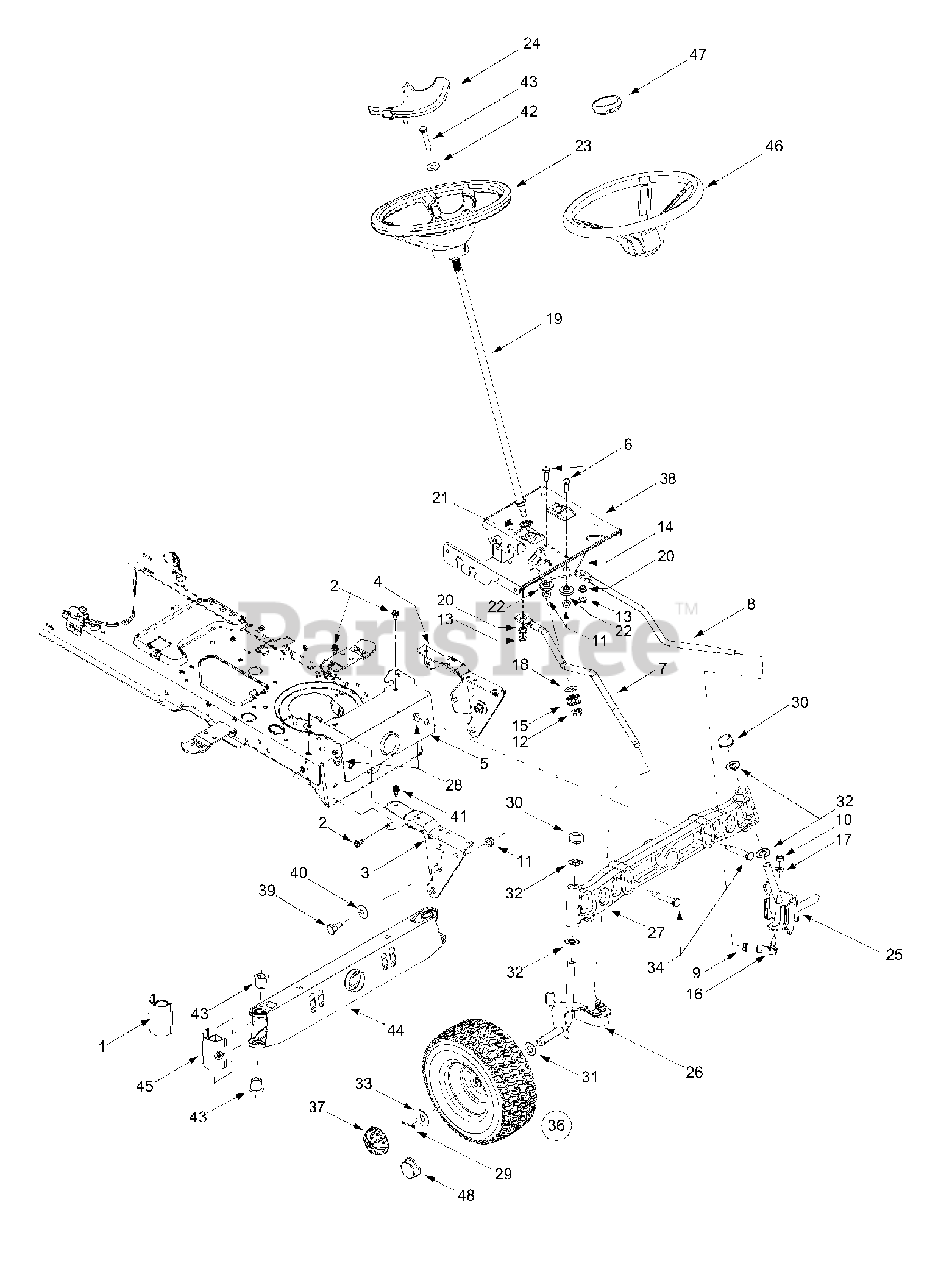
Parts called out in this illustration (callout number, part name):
1	Pivot Bar End Cap w/o Fitting
2	Self-tapping Screw, 16-18 x .625
6	Hex Cap Screw, 3/8-16 x 1 (Grade 5)
7	RH Drag Link
8	LH Drag Link
9	Jam Nut, 7/16-20 (Grade 2)
10	Hex Nut, 3/8-24 (Grade 2)
11	Flange Lock Nut, 3/8-16
12	Flange Lock Nut, 7/16-20
13	Flange Lock Nut, 5/16-18
14	Steering Gear, 11/90 Ratio
15	Steering Pinion Gear
16	Ball Joint, 7/16-20
17	Lock Washer, 3/8
18	Flat Washer, .51 x 1.12 x .06
19	Steering Shaft, .625 OD x 24.4
20	Plastic Bushing, .38 ID
21	Hex Flange Bearing, 5/8
22	Shoulder Spacer, .38 ID
23	Deluxe Steering Wheel
24	Steering Wheel Cap, w/ Icon
25	LH Axle Assembly, .75 Diameter
26	RH Axle Assembly, .75 Diameter
27	Cast Iron Pivot Bar w/ Fittings, .75
28	Flange Lock Nut, 3/8-16
29	Cotter Pin
30	Push Cap, .625
31	Flat Washer, .64 x 1.0 x .12
32	Flat Washer, .78 x 1.59 x .06
33	Flat Washer, .635 x 1.589 x .06
34	Shoulder Screw, .5 x 2.2, 3/8-16
35	Hex Bolt, 5/16-18 X 1
39	Shoulder Screw, 3/8-16
40	Bell Washer, .39 x 1.13 x .062
41	Self-tapping Screw, 5/16-18 x .75
42	Bell Washer, .34 x .872
43	Flange Bearing, .760 ID x .937 OD
45	Pivot Bar End Cap w/ Fitting
46	Standard Steering Wheel, 13.25
47	Steering Wheel Cap, Round
48	Standard Hub Cap
